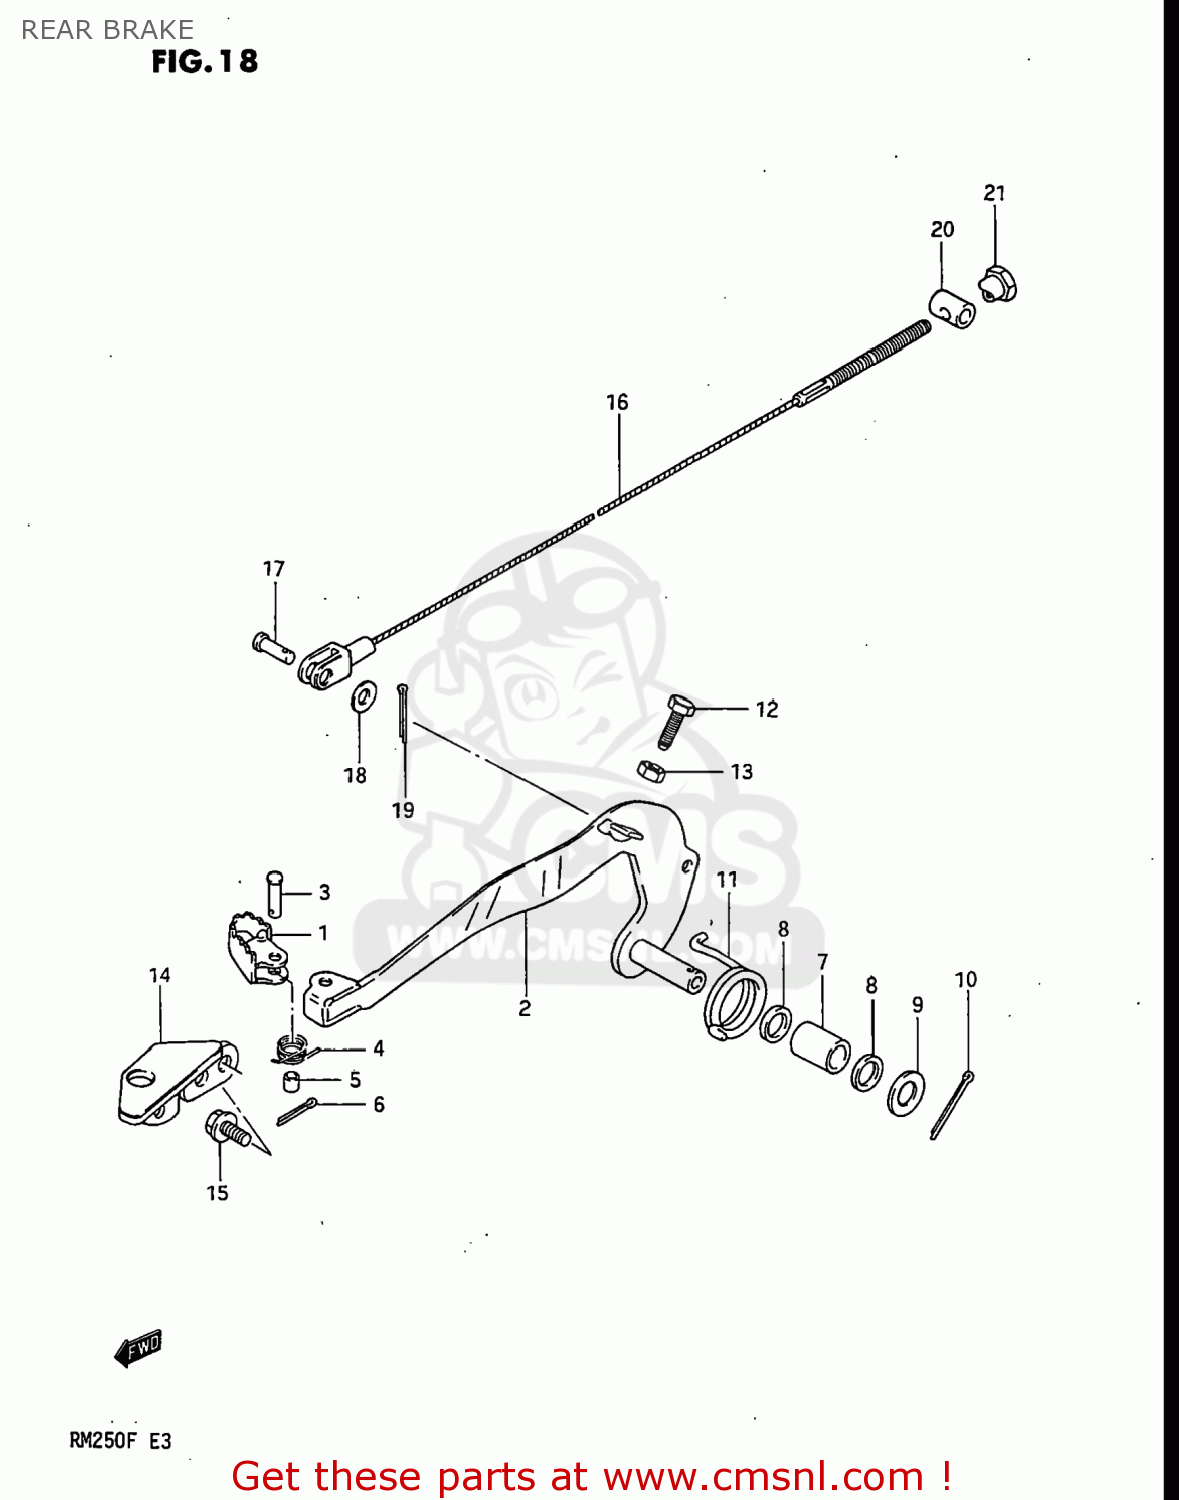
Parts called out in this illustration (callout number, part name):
1	PEDAL,BRAKE
2	ARM,BRAKE PEDAL
3	PIN
4	SPRING
5	SPACER(9.2X9X6.5)
6	PIN
7	BUSHING
8	O RING(D:2.2,ID:11.8)
9	WASHER
10	PIN 30X20
11	SPRING
12	BOLT
13	NUT
14	PROTECTOR,BRAKE PEDAL
15	BOLT
16	CABLE ASSEMBLY,REAR BRAKE
17	PIN(L:17.5)
18	WASHER
19	PIN 20X20
20	PIN
21	NUT (6MM)
